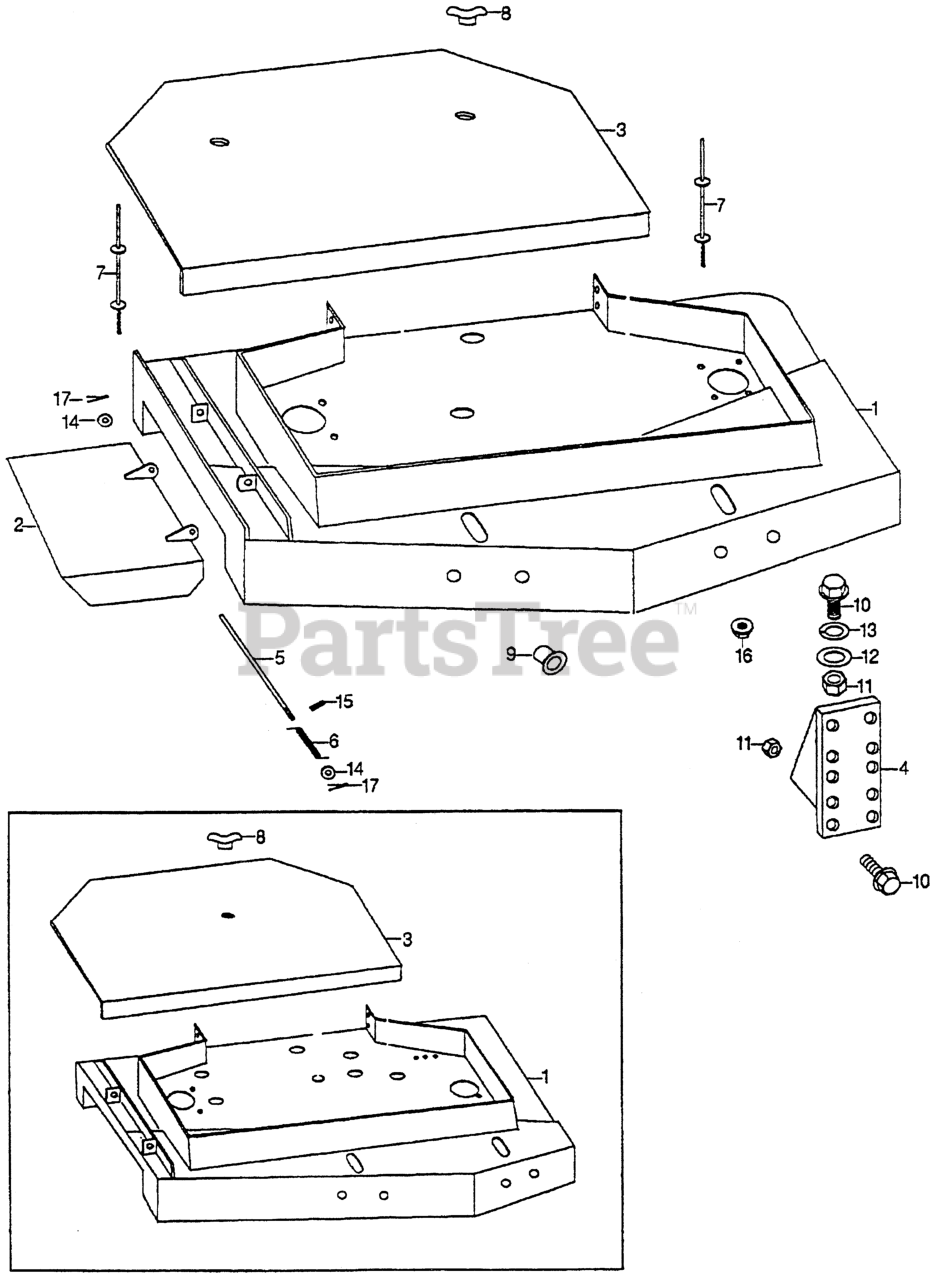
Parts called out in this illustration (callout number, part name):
1	HOUSING, CUTTER (48") (NOT AVAILABLE)
2	ADAPTER, DISCHARGE (NOT AVAILABLE)
3	COVER, BELT (48")
4	BRACKET
5	SHAFT, DISCHARGE
6	SPRING, GUARD SET
7	STUD, HOOD MOUNT
8	WINGNUT (5/16"-18)
9	NUT, INSERT (3/8")
